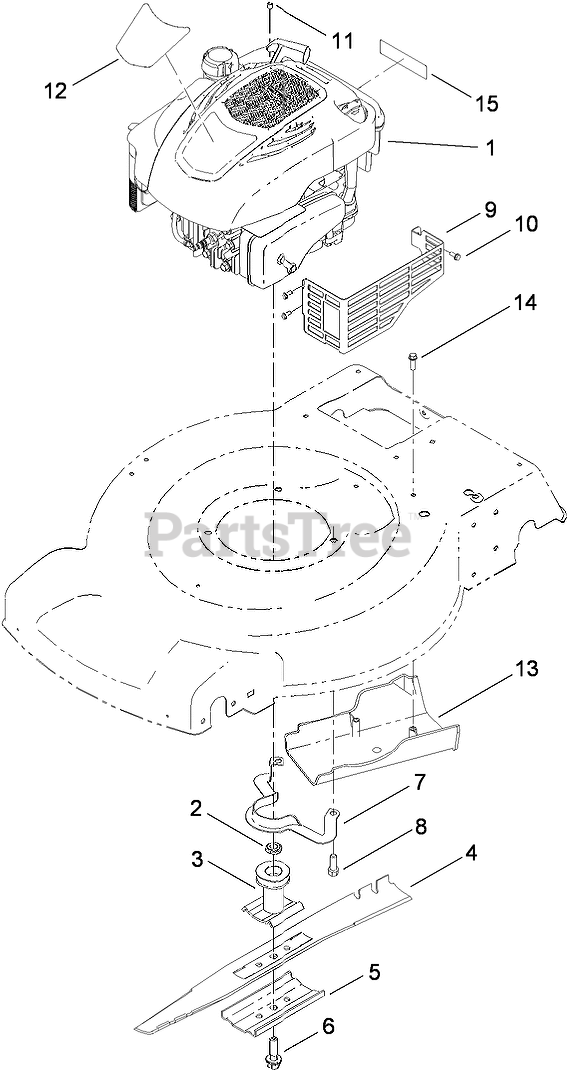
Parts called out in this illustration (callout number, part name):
2	Spacer-Driver
3	DRIVER-BLADE
4	BLADE-22 INCH
5	SUPPORT-BLADE
6	BOLT-BLADE
7	Guide-Belt
8	SCREW-TAPTITE
9	SHIELD-MUFFLER
10	SCREW-TAPTITE
11	STOP-ROPE
12	DECAL-SHROUD
13	COVER-BELT
14	SCREW-HWH
15	DECAL-ARRESTER, SPARK
